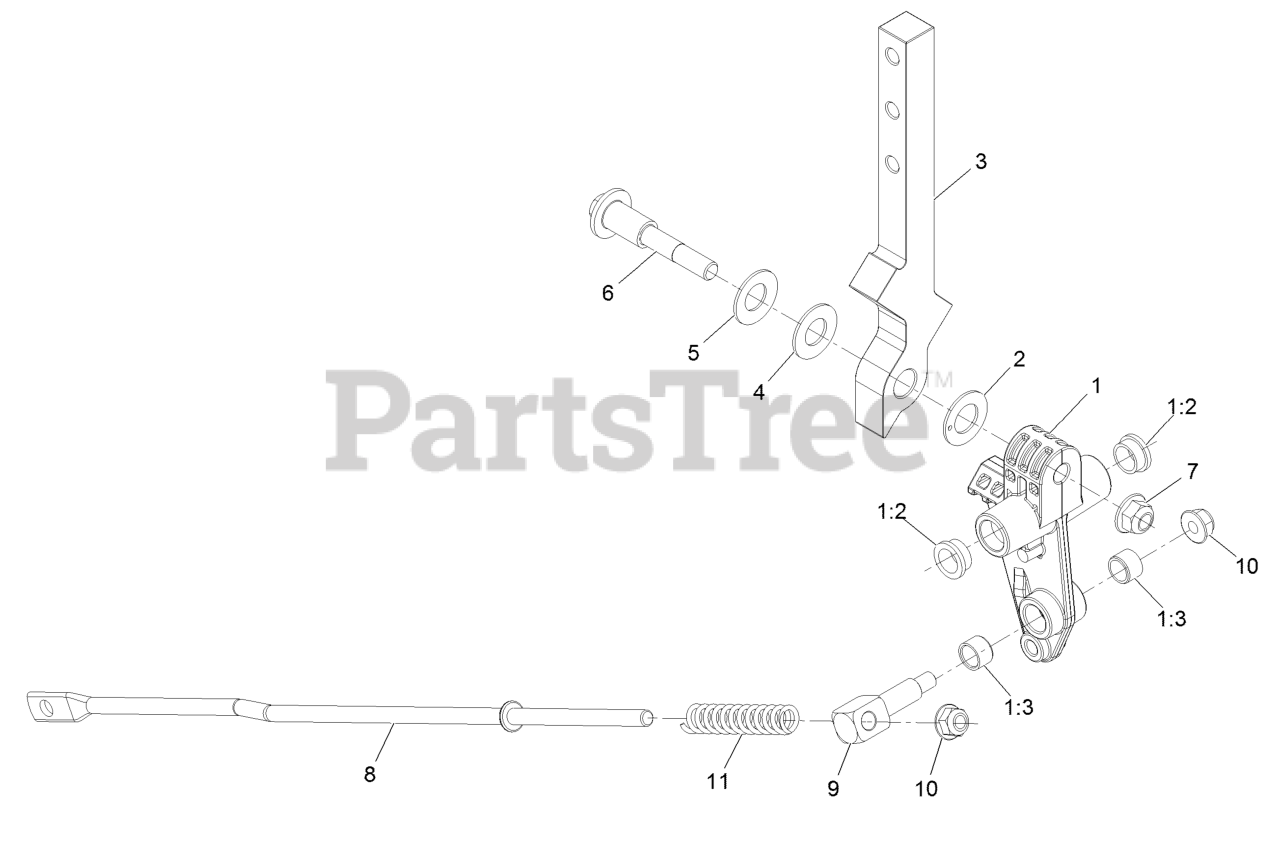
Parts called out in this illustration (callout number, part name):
1	Control Arm ASM
1:2	Bushing-Pm
1:3	Bushing-Sleeve
2	Washer, Friction
3	Arm-Control
5	Washer-Belleville
6	Bolt-Pivot
7	Nut-Nyloc 3/8-16 Flg
8	Link-Control
10	Nut-Nyloc 5/16-18 Flg
11	Spring-Return, Neutral
